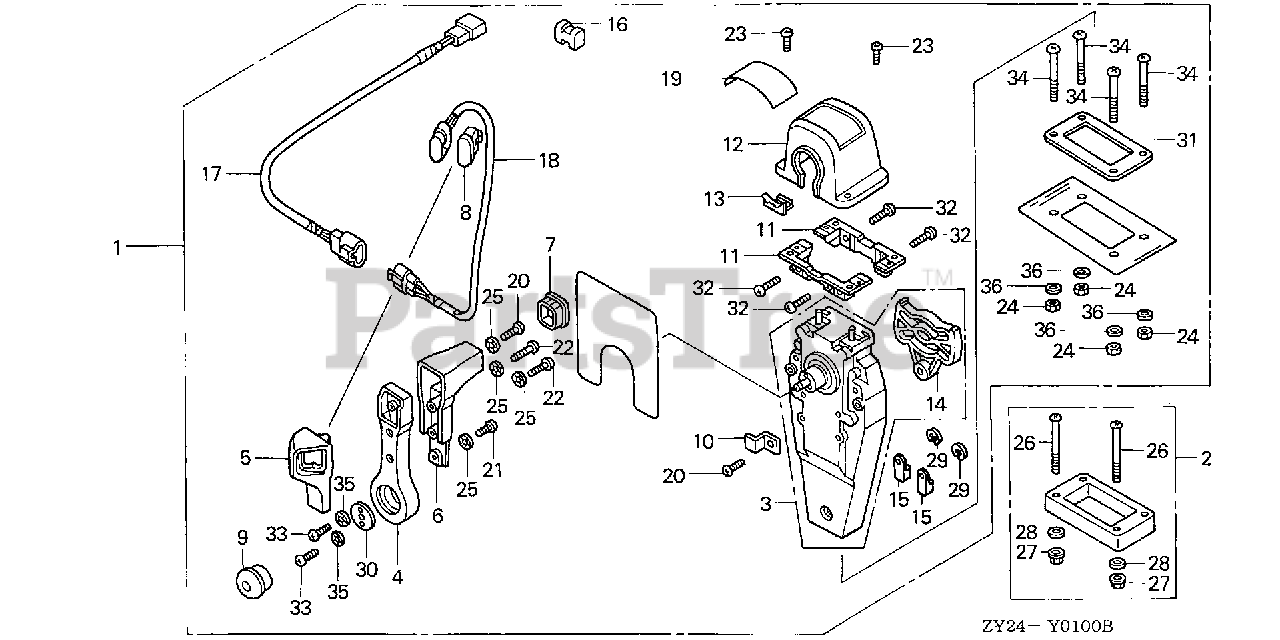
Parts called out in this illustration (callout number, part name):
1	BOX KIT, REMOTE CONTROL (TOP MOUNT SINGLE)(R)
2	SPACER KIT, REMOTE CONTROL BOX (TOP MOUNT SINGLE)
3	HOUSING ASSY., L. (INNER) (TOP MOUNT)
4	HANDLE, REMOTE CONTROL
5	COVER, L. GRIP
6	GRIP, REMOTE CONTROL HANDLE
7	CAP, GRIP
8	CAP, SWITCH
9	BUTTON, THROTTLE
10	PLATE, CABLE CLAMP
11	BRACKET, REMOTE CONTROL HOUSING
12	HOUSING, REMOTE CONTROL BOX
13	HOUSING, LEAD
14	PLATE, DWELL
15	TERMINAL, CABLE
16	SPACER, CABLE CLAMP
17	SUB-HARNESS ASSY., POWER TRIM-TILT (A)
18	SWITCH ASSY., POWER TRIM-TILT (A)
19	MARK, REMOTE CONTROL (SINGLE)
20	SCREW, PAN (5X16)
21	SCREW, PAN (5X10)
22	SCREW, PAN (5X20)
23	SCREW, PAN (4X10)
24	NUT, HEX. (5MM)
25	WASHER, LOCK (5MM)
26	SCREW, PAN (5X65)
27	NUT, FLANGE (5MM)
28	WASHER, PLAIN (5MM)
29	E-RING (6MM)
30	PLATE, HANDLE
31	GASKET, SINGLE
32	SCREW, PAN (5X18)
33	SCREW, PAN (6X18)
34	SCREW, PAN (5X40)
35	WASHER, LOCK (6MM)
36	WASHER, PLAIN (5MM)
